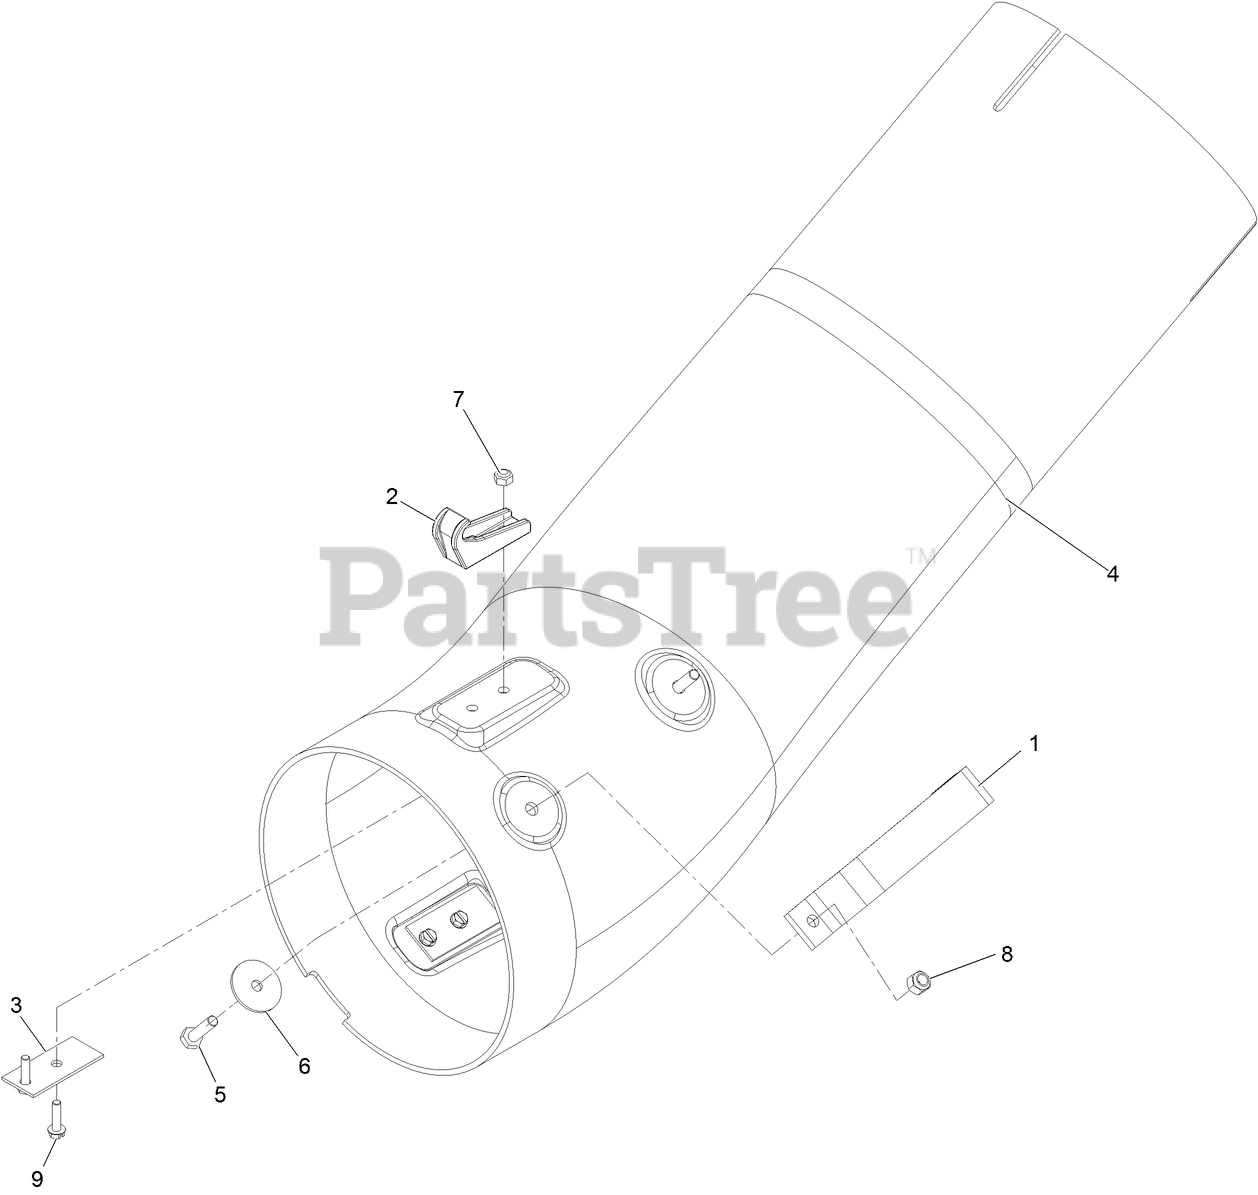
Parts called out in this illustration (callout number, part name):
2	LATCH-CATCH
3	PLATE-BACKING
4	Chute, Lower
5	SCREW-HH
6	WASHER-FLAT
7	NUT-LOCK, NI
8	NUT-LOCK, NI
9	SCREW-HWH
